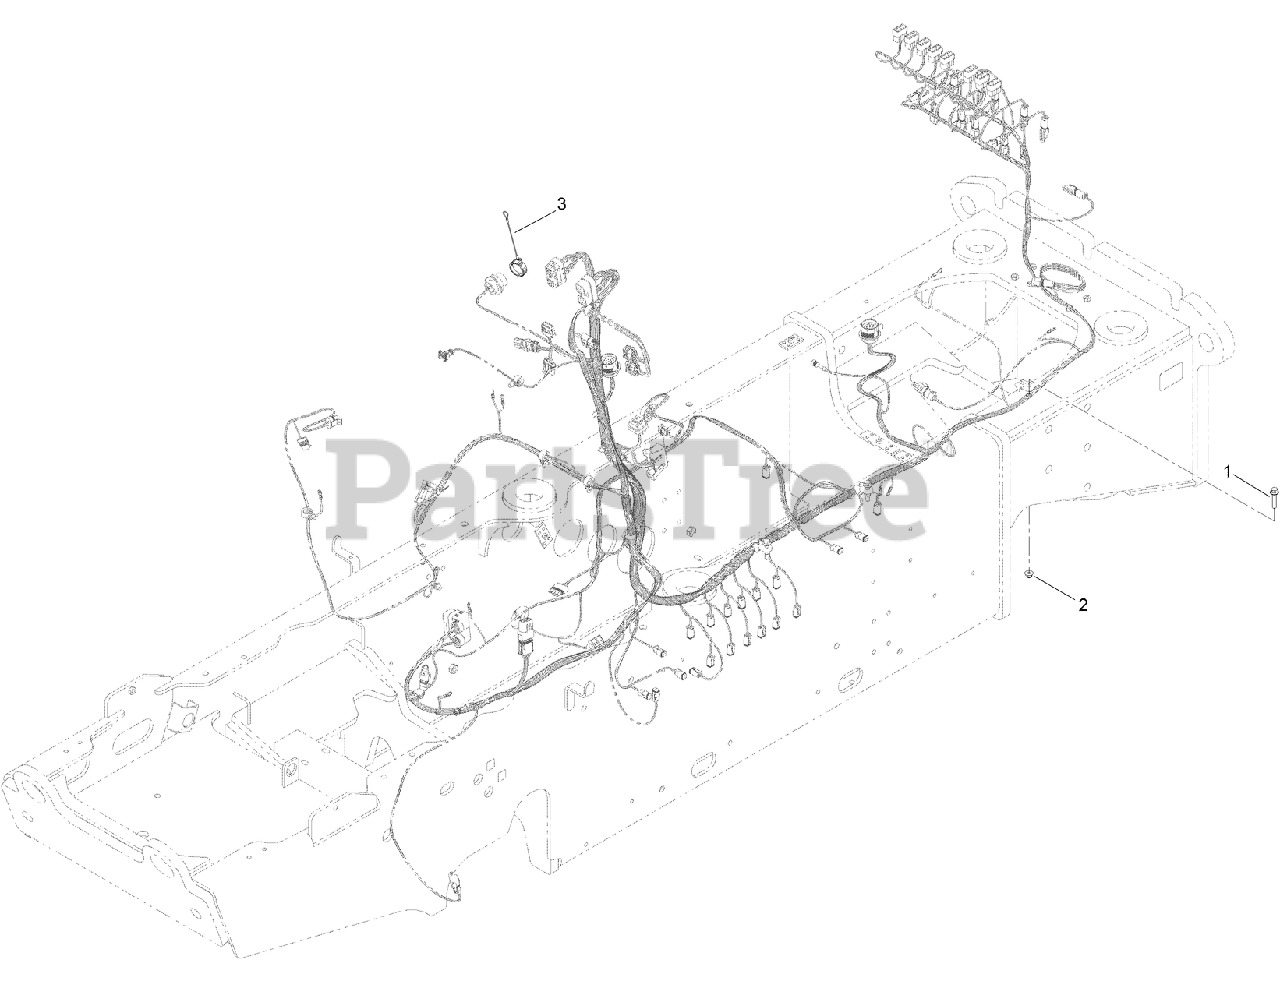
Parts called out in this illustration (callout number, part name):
1	SCREW-HHF
2	NUT-HF, NI
3	CAP-DIAGNOSTIC
